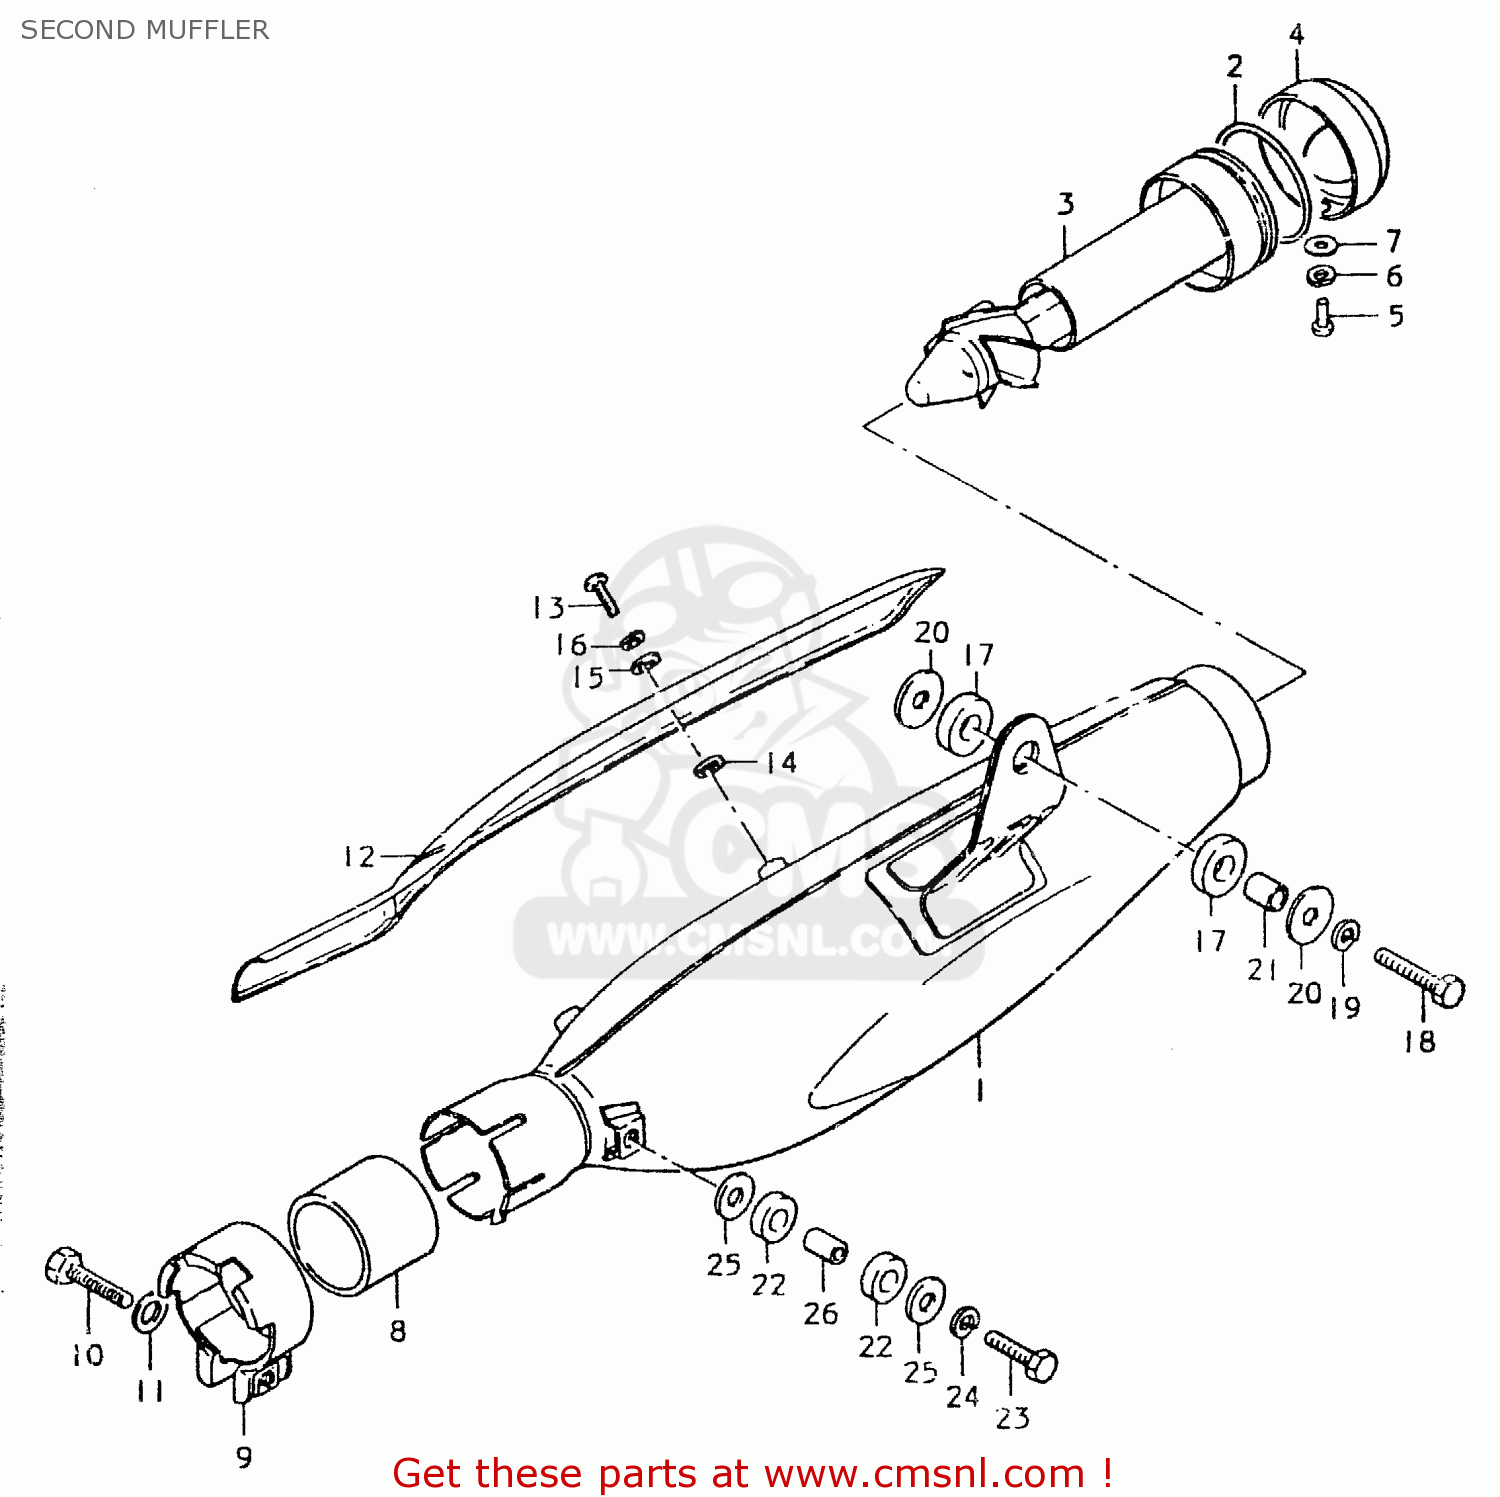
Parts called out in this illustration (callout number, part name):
1	MUFFLER ASSEMBLY
2	O-RING (D:3.5 ID:54.4)
3	TUBE,MUFFLER CLEAN OUT
4	COVER,SECOND MUFFLER TAIL
5	SCREW(6X8)
6	LOCK WASHER
7	WASHER
8	CONNECTOR,MUFFLER
9	CLAMP
10	BOLT 8X35
11	WASHER
12	COVER,SECOND MUFFLER
13	SCREW 6X12
14	GASKET 6.2X12X1.5 (MCA)
15	WASHER
16	LOCK WASHER
17	CUSHION
18	BOLT (8X30)
19	LOCK WASHER
20	WASHER (8.5X29X1.6)
21	SPACER (8.6X13.8X13)
22	CUSHION
23	BOLT
24	LOCK WASHER
25	WASHER
26	SPACER (8.6X13.8X8)
